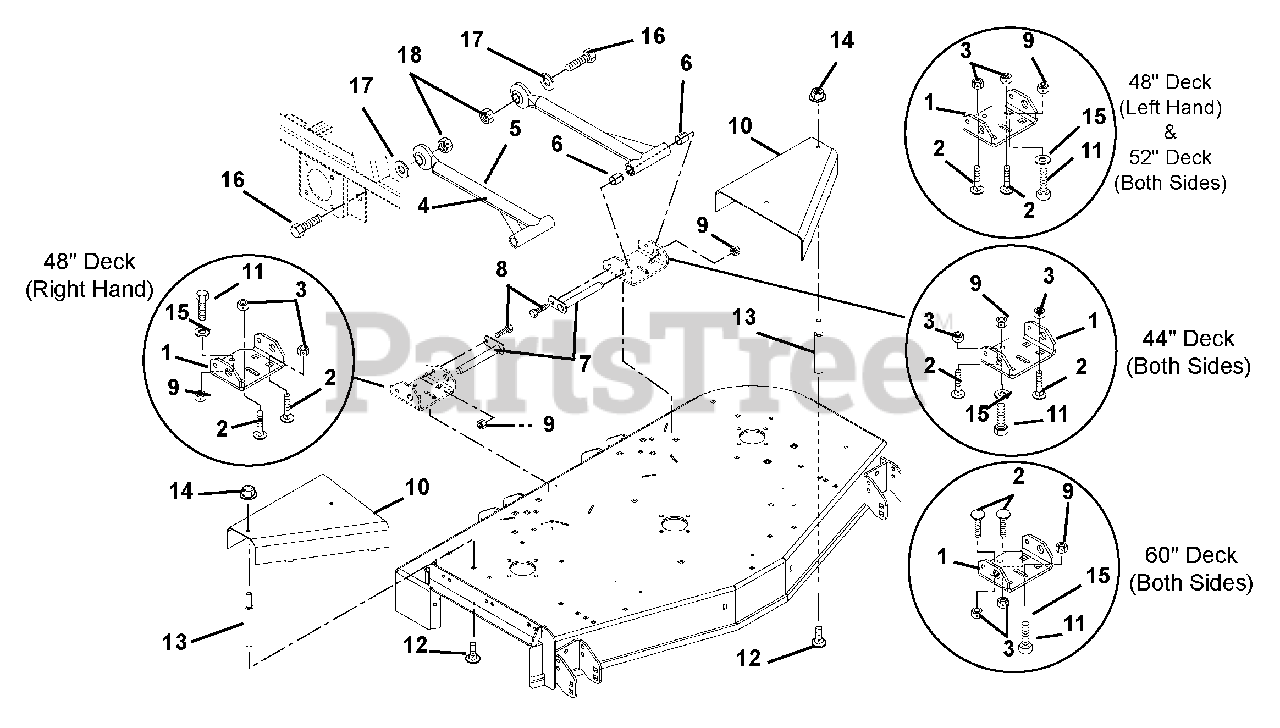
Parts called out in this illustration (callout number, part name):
1	Bracket, Mower Mounting (Rear)
2	Bolt, Round Head Square Neck .50-13 x .75 Grade 5
3	Nut, Locking Center Jam .50-13
4	Assembly, Mower Mounting
5	Mower Mounting Arm
6	Bearing, .75 x .875 x 1.00
7	Weldment, Mower Mounting Pin
8	Bolt, Hex .38-16 x .75 Grade 5
9	Nut, Locking Top Flange .38-16
10	Guard, Pulley Left Hand
10	Guard, Pulley Right Hand
10	Guard, Pulley
11	Bolt, Round Head Square Neck .38-16 x .75 Grade 5
12	Bolt, Round Head Square Neck .31-18 x .75
13	Standoff, 2.75 x .312-18
14	Nut, Locking Top Flange .31-18
15	Washer, Flat Steel .406 x .812 x .065
16	Bolt, Hex .875-9 x 2.75 Grade 5
17	Washer, Flat Steel .875 x 1.50 x .120
18	Nut, Locking Center .875-9
